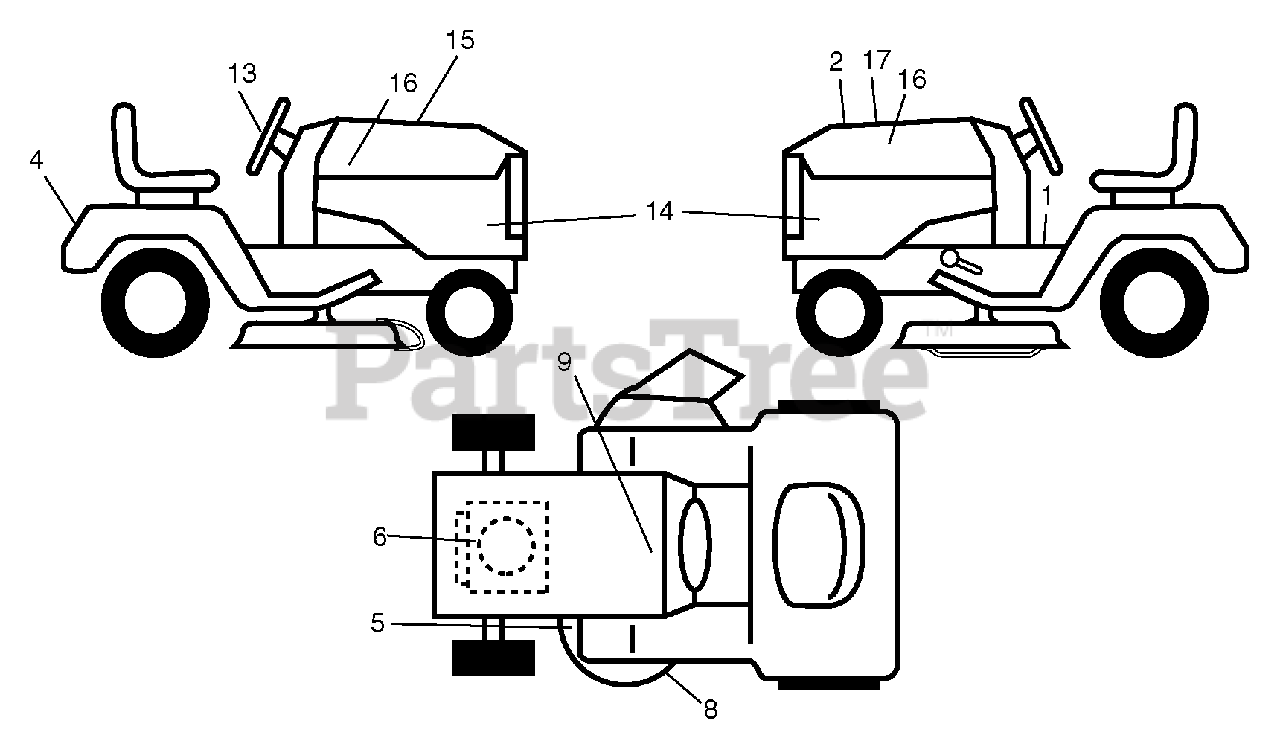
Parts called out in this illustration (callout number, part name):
1	Decal, Operator's
2	Decal, Hood Insert
4	Decal, Fender
5	Decal, Caution
6	Decal, Eng. HP
8	Decal, Mower Sch.
9	Decal, Battery Dnge/Poi
13	Decal, Steering Whl
14	Decal, Panel Side
15	Decal, Cust. Resp.
16	Decal, Hood Logo
17	Decal, Replacement
